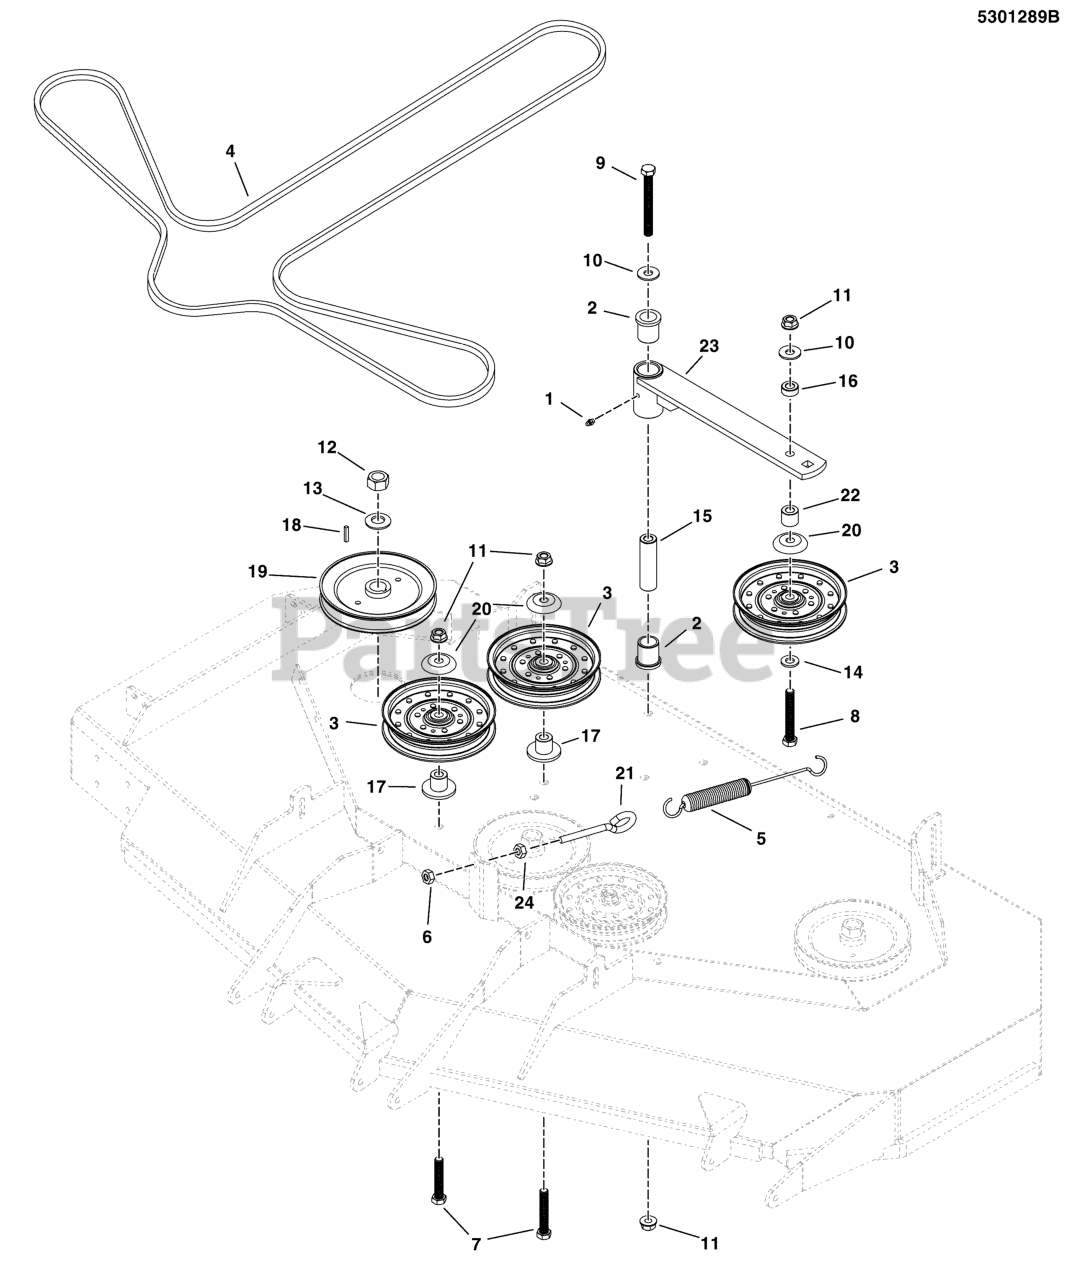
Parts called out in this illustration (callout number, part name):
1	GREASE FITTING, 1/4-28 STRAIGHT
2	BUSHING, FLANGE
4	BELT, 5V, 175.90EL, LG ARAMID, WRPD, RC
5	SPRING-EXTENSION, SWIVEL END
6	NUT, 3/8-16 HEX NYLOCK FLANGE
7	BOLT, 1/2-13 X 3" GD5 CZ
8	BOLT, 1/2-13 X 3-1/2, HEX HD, GD5, CZ (SV)
9	BOLT, 1/2-13 X 4-1/2 GD5
10	WASHER, 1/2 USS
11	NUT, Hex Flange, Nylock, 1/2-13
12	NUT, 3/4-16 HEX
13	WASHER, 3/4 BELLEVILLE
14	WASHER, 1/2 GD9 YZ
15	SPACER, .52 X 1.00 X 3.50
16	SPACER, .52 X 1.00 X .44
17	IDLER MOUNT
18	KEY, 1/4 SQ. X 1-1/4
19	PULLEY, 6.93 EOD X 25MM, SPLIT
20	SHIELD, PULLEY BEARING
21	EYE BOLT, 3/8-16 X 5, 2.88THRD, 1EYE, CZ
22	SPACER, .52 X 1.00 X .88
23	ASSM, IDLER ARM
24	NUT, 3/8-16 HEX JAM
